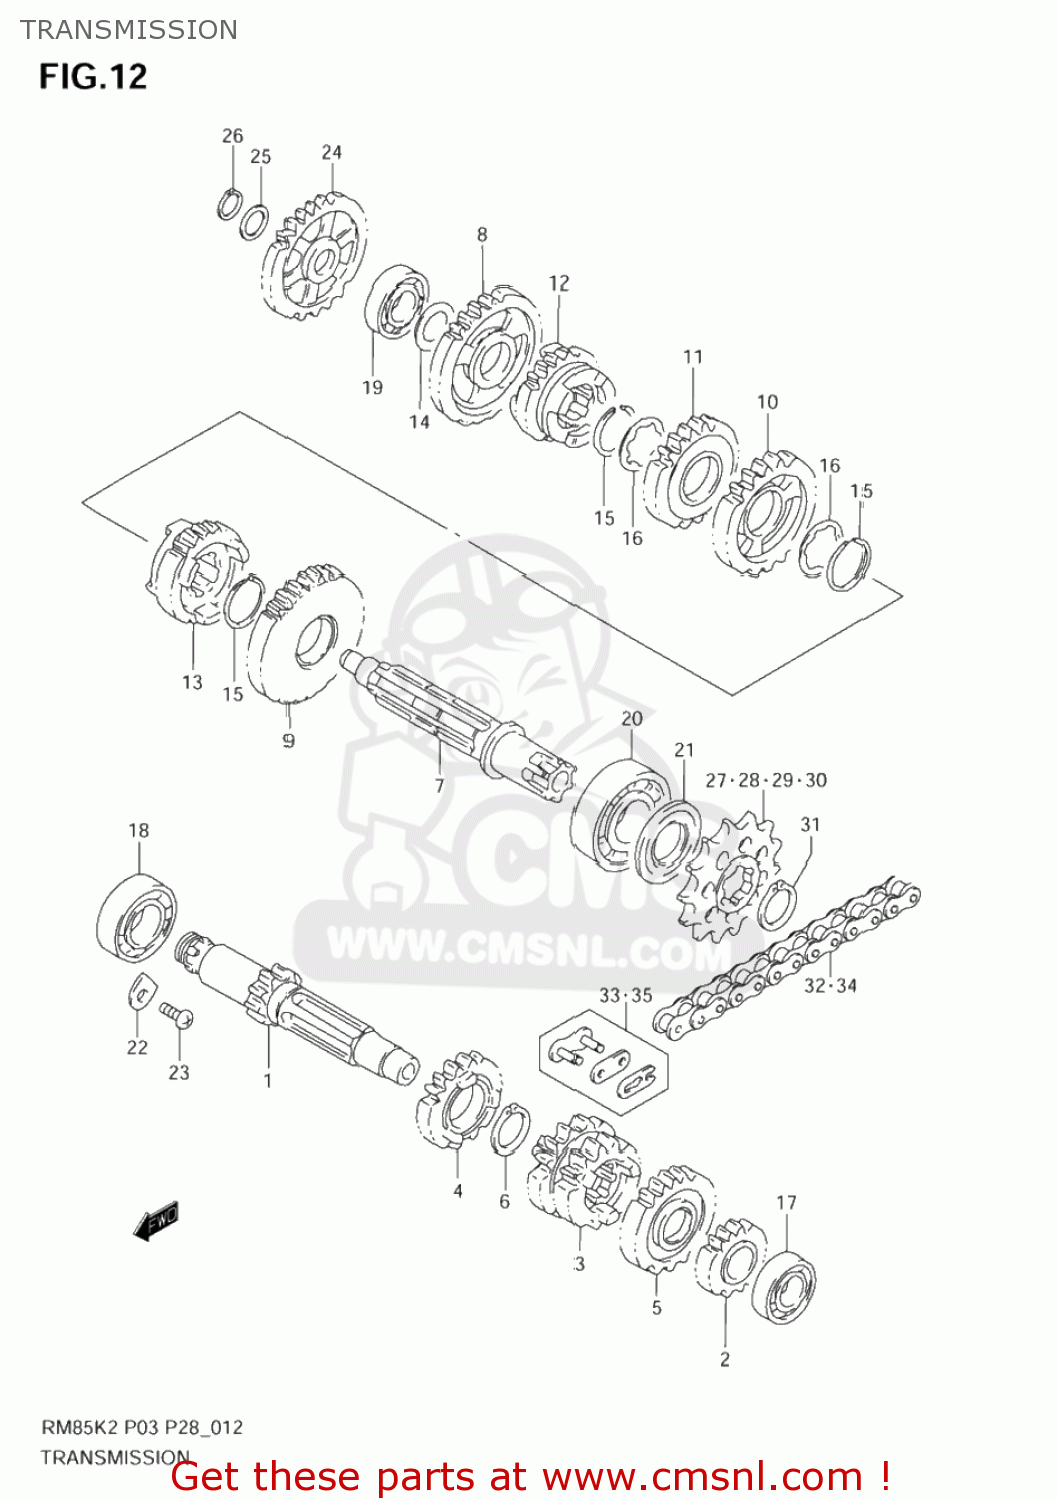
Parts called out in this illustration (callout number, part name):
1	SHAFT,COUNTER(NT:11)
2	GEAR,2ND DRIVE(NT:15)
3	GEAR,3RD & 4TH DRIVE(NT:14/15)
4	GEAR,5TH DRIVE(NT:18)
5	GEAR,6TH DRIVE
6	CIRCLIP
7	SHAFT,DRIVE
8	GEAR,1ST DRIVEN(NT:28)
9	GEAR,2ND DRIVEN(NT:29)
10	GEAR,3RD DRIVEN(NT:22)
11	GEAR,4TH DRIVEN(NT:20)
12	GEAR,5TH DRIVEN(NT:21)
13	GEAR,6TH DRIVEN(NT:23)
14	SHIM(15X26X1)
15	CIRCLIP
16	WASHER,LOCK
17	BEARING
18	BEARING(20X42X12)
19	BEARING
20	BEARING(20X47X14)
21	SEAL,OIL(20X35X5)
22	RETAINER
23	SCREW
24	GEAR,KICK STARTER IDLE(NT:24)
25	SHIM(12X20X0.5)
26	CIRCLIP,12 MM
27	SPROCKET,ENGINE(NT:14)
28	SPROCKET,ENGINE(NT:13)
29	SPROCKET,ENGINE(NT:13)
30	SPROCKET,ENGINE(NT:12)
31	CIRCLIP
32	CHAIN,DRIVE(428G2X118L)
33	JOINT SET,CHAIN
34	CHAIN,DRIVE(DID428DS,118L)
35	JOINT SET,CHAIN
